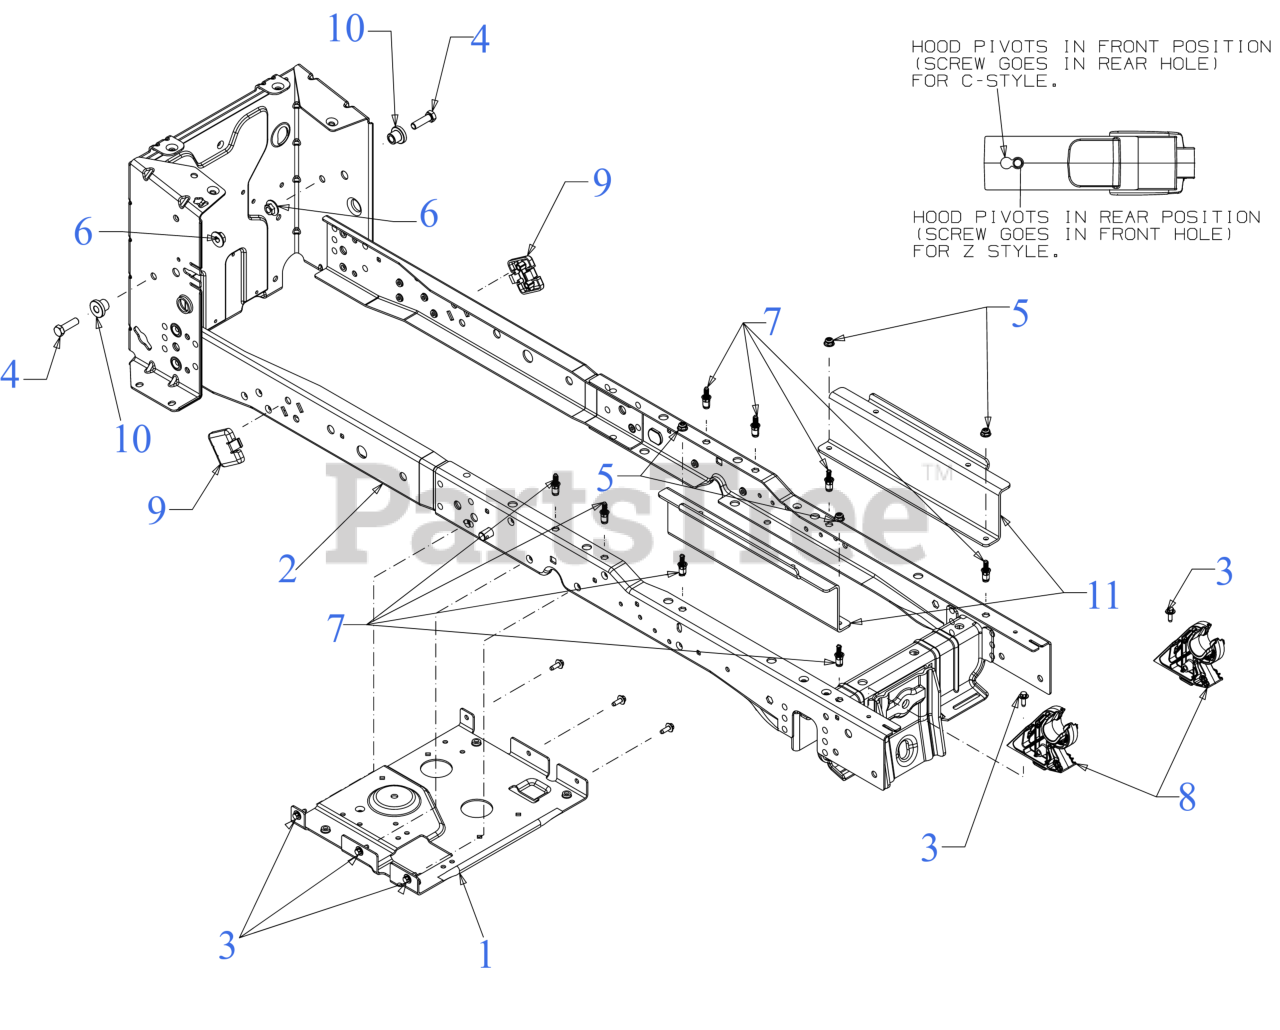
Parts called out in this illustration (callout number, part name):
1	FRAME BRACE BRACKET (LOWER)
2	FRAME
3	SCREW M6-1 x .625
4	SCREW 3/8-16 x 1.25 GR5
5	FLANGE LOCK NUT
6	FLANGE LOCK NUT
7	RIVET-HEX STUD 1/4-20 FRM
8	HOOD PIVOT BRACKET
9	LIFT ROD WEAR PAD
10	SHOULDER SPACER
11	BATTERY BRACKET
